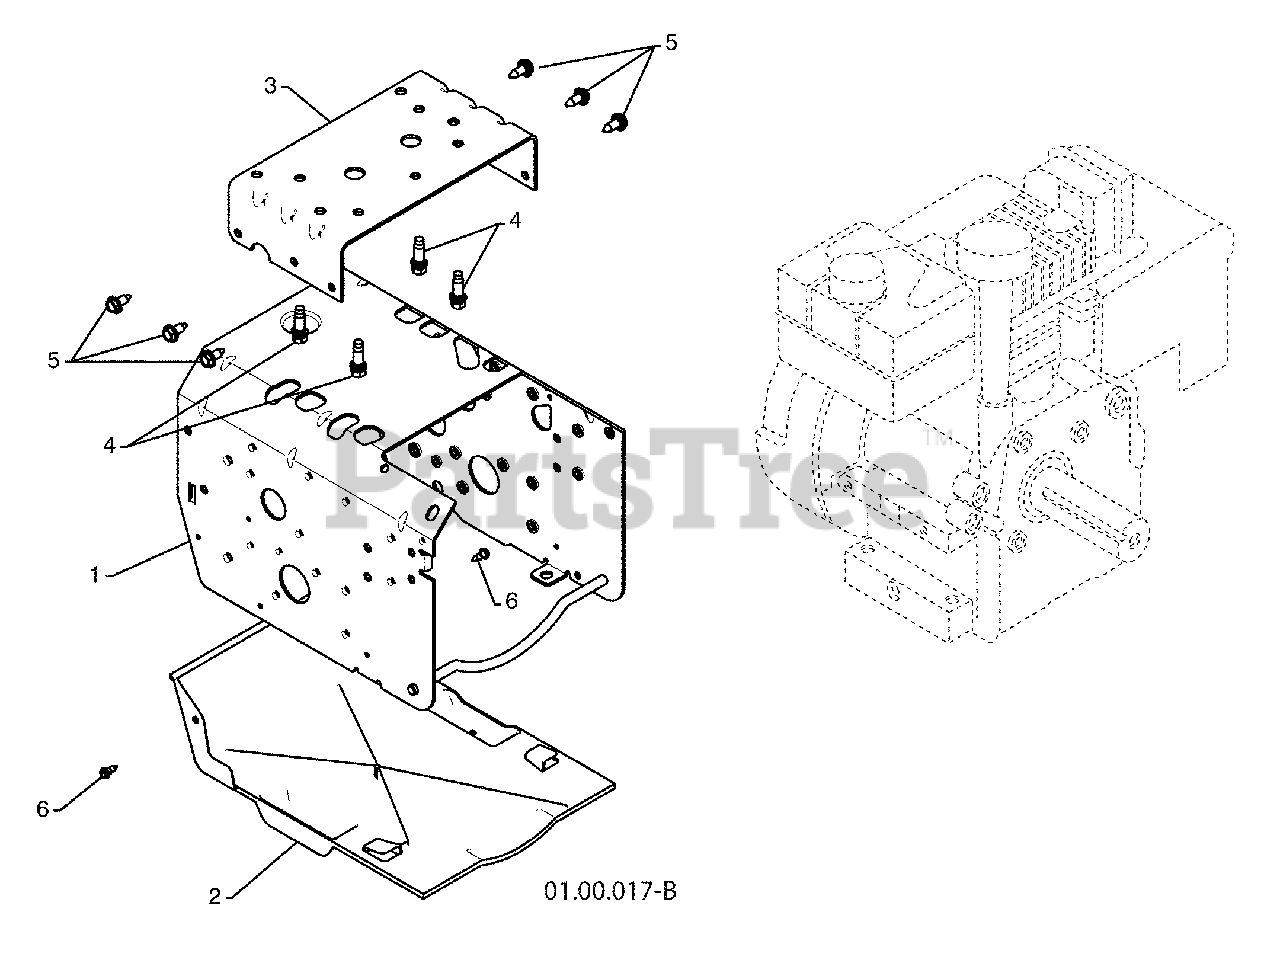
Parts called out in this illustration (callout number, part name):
2	BOTTOM PAN
3	ENGINE MOUNT PLATE
4	BOLT 3/8--16
5	SCREW 5/16--18 X .750
6	SCREW 10--24 X .625
